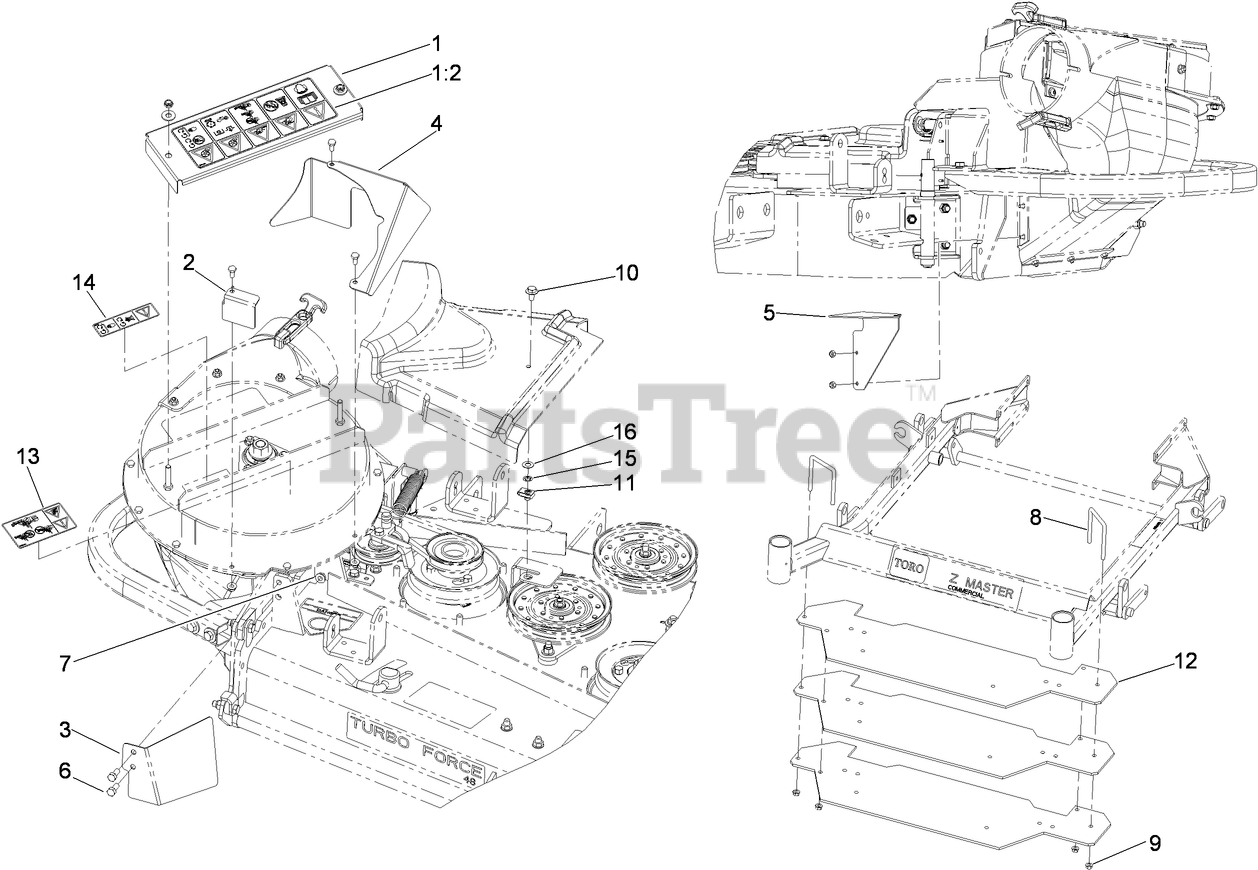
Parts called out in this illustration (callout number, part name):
1	COVER-BEARING
1:2	DECAL-DANGER
2	GUARD-LEFT
3	GUARD-FRONT
4	GUARD-BACK
5	GUARD-LOWER
6	SCREW-HH
7	NUT-HF
8	U-BOLT (4 INCH)
9	NUT-HF
10	SCREW-HHF
11	NUT-U
12	PLATE-WEIGHT
13	DECAL-WARNING
14	DECAL-MISSING, COVER
15	NUT-PUSH
16	WASHER-THRUST
